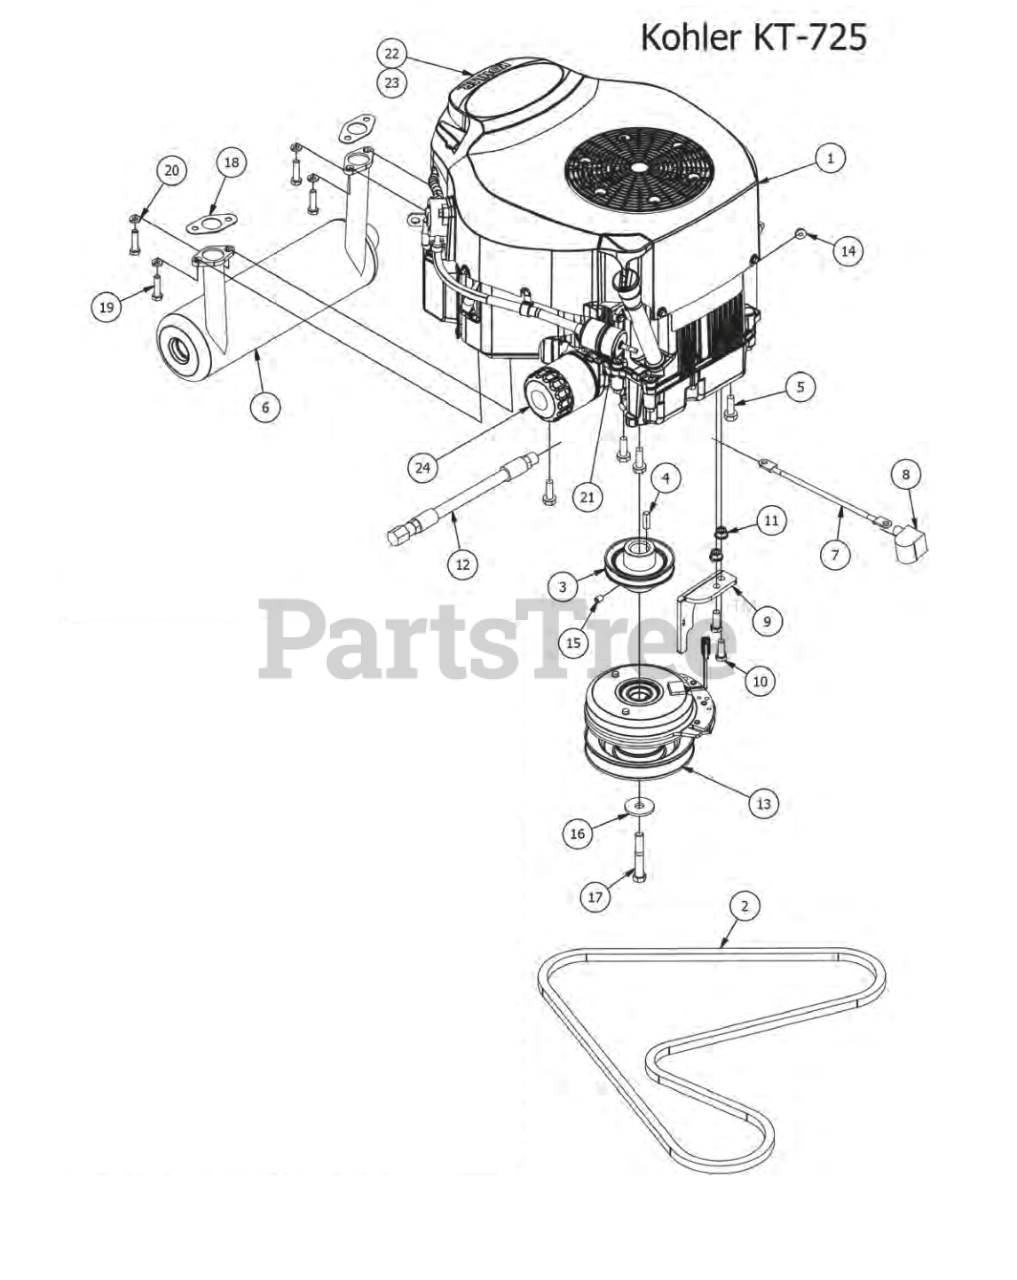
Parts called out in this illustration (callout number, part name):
1	Kohler KT-725
3	3-3/4" Motor Pulley
4	1/4" x 1" Key
5	3/8 x 1 1/8 bolt
6	2014 MZ Muffler-725cc Kohler
7	Ground Cable
8	Black Boot For ground cable
9	Warner Clutch A-R Bracket
10	3/8" x 1" Hex Bolt
11	3/8" Nylock Flange Nut
12	Oil drain Hose
13	Clutch 2015 Magnum/MZ
14	1/4-20 Hex Flange Nuts Zinc w/Serrations
15	3/8" Set Screw
16	1/2 Belleville Washer
17	7/16" x 2 3/4" Fine Thread Bolt
18	Exhaust Gasket
19	5/16 x 1 1/4 Hex Bolt
20	5/16" Lock Washer
21	KT-725 & KT-740 Fuel Filter
22	KT-725 & KT-740 Precleaner
23	KT-725 & KT-740 Air Elemet
24	KT-725 & KT-740 Oil Filter
